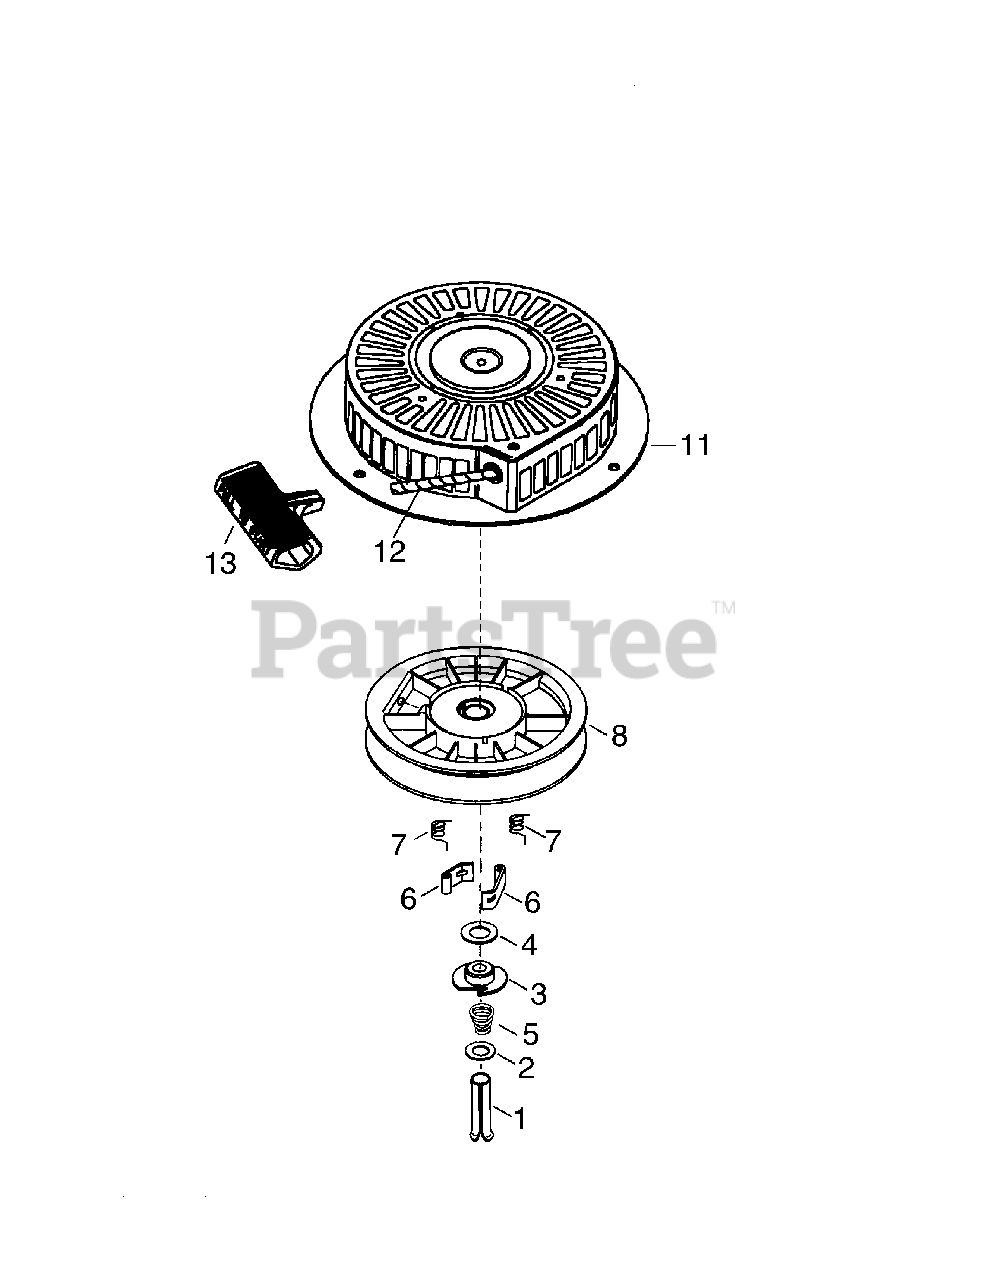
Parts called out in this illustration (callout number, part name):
5	Brake Spring
6	Starter Dog
7	Dog Spring
8	Pulley & Rewind Spring Assy.
11	Starter Housing Assy.
12	Starter Rope
13	Mitten Grip Handle
